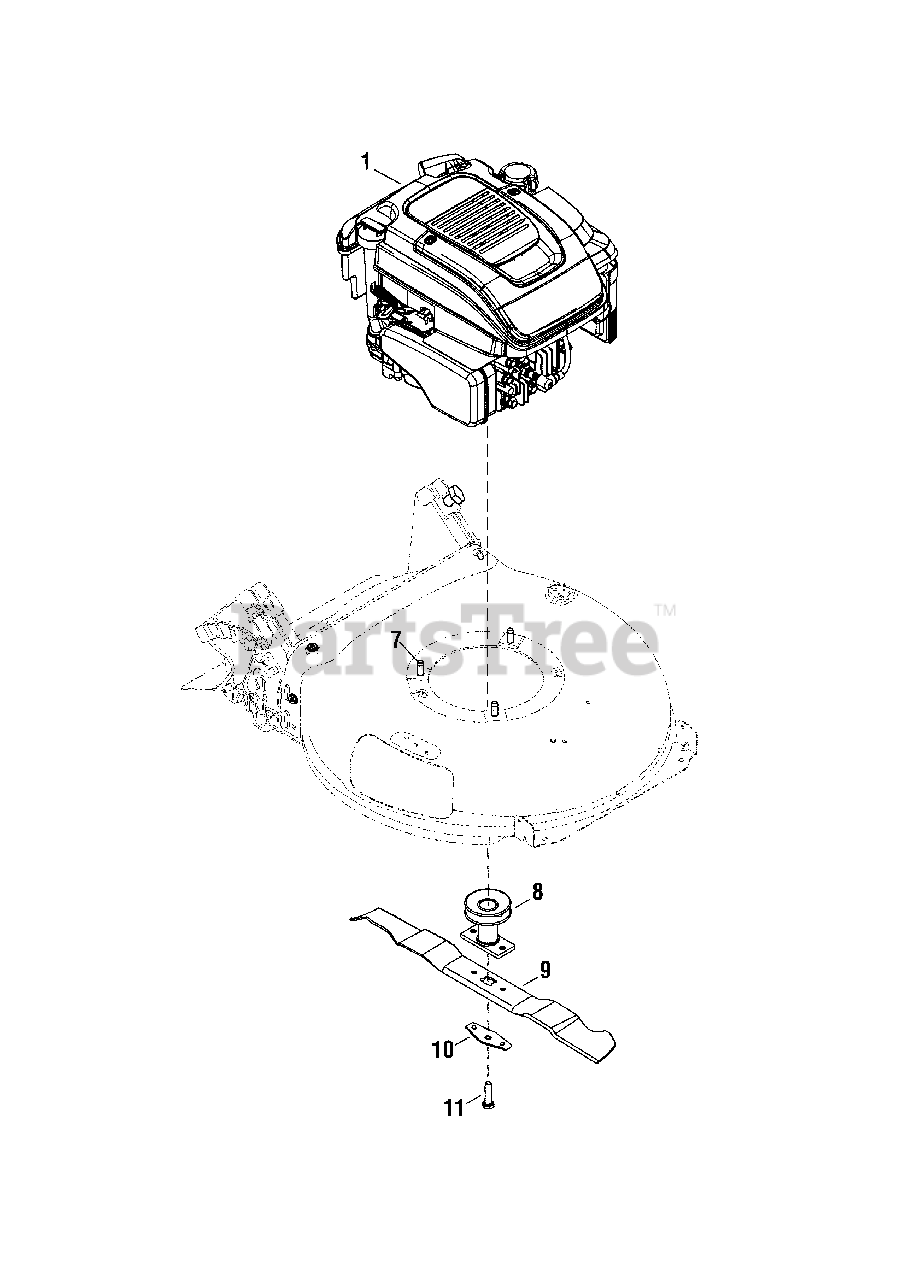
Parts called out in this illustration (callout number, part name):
1	* ENGINE, Briggs & Stratton, Mod. 128M02-0136-F1
1	* ENGINE, Briggs & Stratton, Mod. 103M02-0004-F1
7	SCREW, Engine Mounting, 3/8-16 x 1
8	ADAPTER, Blade
9	BLADE, Mulching
10	SUPPORT, Blade Bell
11	SCREW Hex, 3/8-24 x 1-1/2
